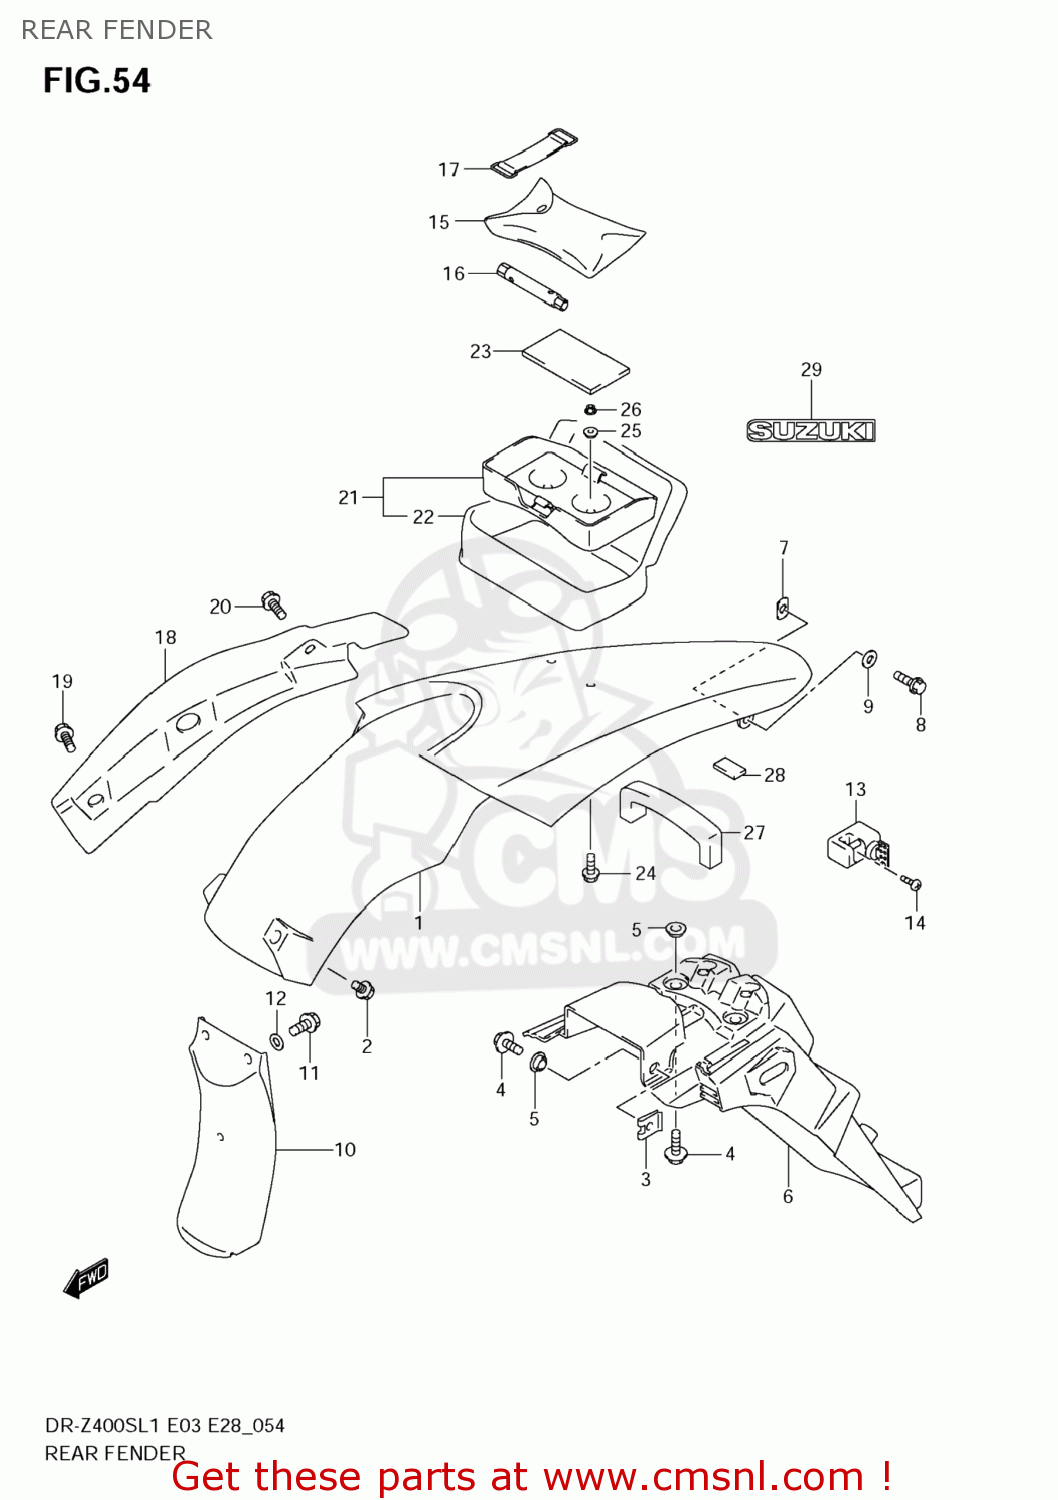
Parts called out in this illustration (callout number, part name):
1	FENDER,RR
2	BOLT(6X16)
3	PLATE,RR FENDER
4	BOLT(6X20)
5	WASHER
6	EXTENSION,RR FENDER
7	NUT,COWL
8	BOLT
9	WASHER
10	MUDGUARD,RR FENDER FR
11	BOLT
12	WASHER
13	LOCK SET,HELMET
14	SCREW(6X14)
15	TOOL ASSY
16	SPARK PLUG WRENCH(8X10)
17	BAND
18	MUDGUARD,RR FENDER,R
19	BOLT(6X18)
20	BOLT
21	BAG ASSY,SEAT TAIL
22	BAG,SEAT TAIL
23	CUSHION,RR BAG
24	BOLT
25	WASHER
26	NUT
27	SEALER,SIDE COVER L
28	PROTECTOR(170X95X3.0)
29	EMBLEM,SUZUKI
